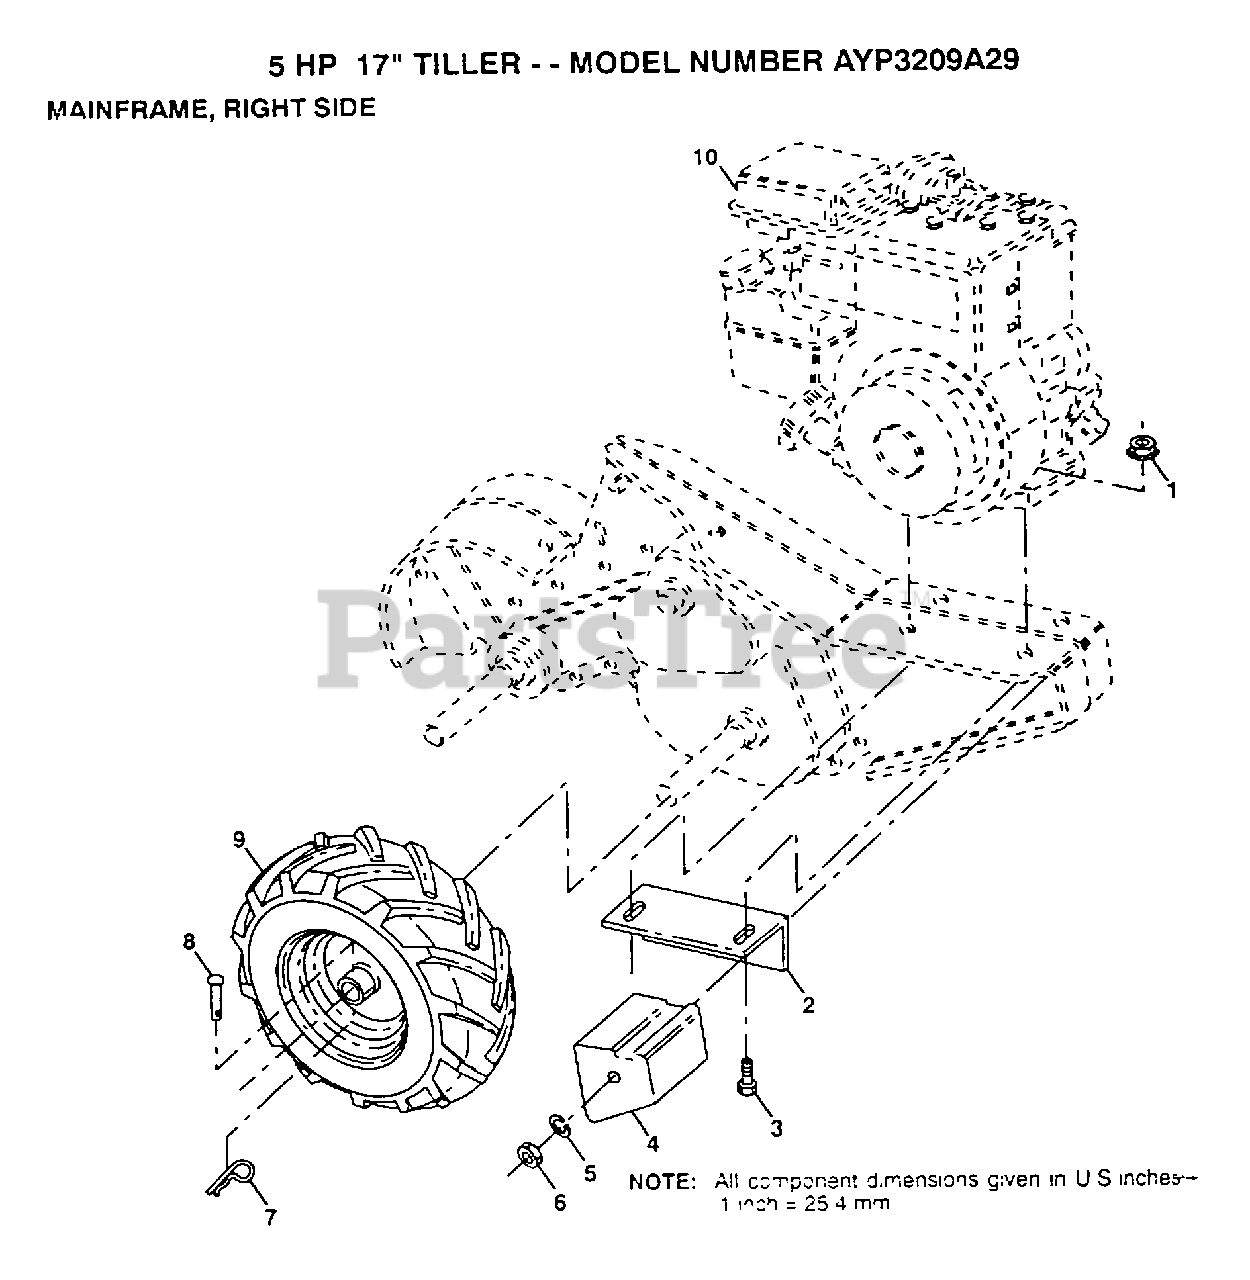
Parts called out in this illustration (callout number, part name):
2	BRACKET RH CRT
3	BOLT.HEX.5/16-1.5
4	COUNTERWEIGHT CRT
5	LOCKWASHER
6	NUT.HEX.3/8-16UNC
7	RETAINER M
8	RIVET.DRILL.1.75
9	TIRE TI
10	ENGINE, SEE BREAKDOWN
